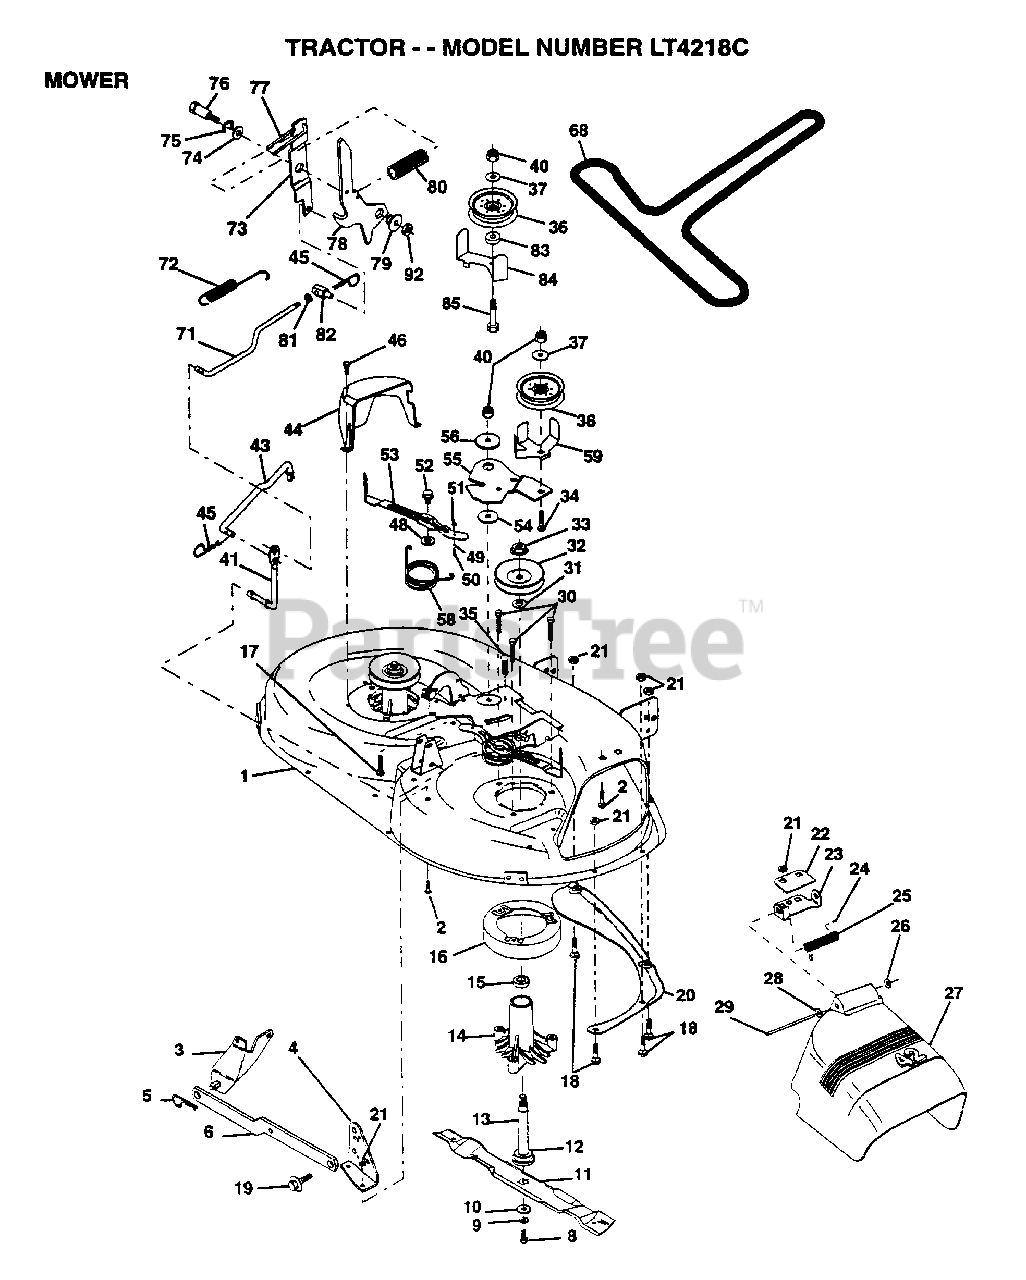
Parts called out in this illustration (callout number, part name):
1	DECK.WELD.42.
2	BOLT
3	BRKT ASM SWAY BAR
4	BRKT DECK SW BAR
8	BLADE BOLT
10	WASHER.HARD.BLADE
11	"BLADE.42"" HIPERF"
12	BEARING.BALL
14	HSG ASM MANDREL
15	BEARING
16	STRIPPER RND MWR
17	BOLT RDHD 3/8-16
18	BOLT
19	BOLT SHD 5/16-18
22	STIFFENER BRKT
23	DEFLECTOR BRKT
24	CAP-SLEEVE LT
25	SPRING TORSION
26	NUT PUSH M
27	DEFLECTOR.SHIELD
28	WASHER
29	HINGE ROD
31	WASHER
34	BOLT
35	XMAS TREE FASTNER
36	FLAT IDLER PULLEY
37	WASHER
41	PIVOT ROD
43	ROD CLUTCH W/NIBS
44	GUARD MAND LH BLK
45	RETAINER M
46	SCREW.1/4-20X5/8
48	HARD SMALL WASHER
50	SHOULDER BOLT
51	LOCKNUT
52	BOLT.SHLD.5/16-18
53	BRAKE PAD ARM ASM
54	HARDENED WASHER
56	SPACER RETAINER
58	SPRING TORSN BRAK
59	GUARD IDLER TUV
68	BELT.V.T-PATH
71	ROD CLUTCH 38/42
72	SPRING.EXT.RETURN
73	CLUTCH ARM SECOND
74	WASHER
75	RING
76	SHOULDER BOLT
77	SPRING KEEPER
79	BUSHING
81	NUT
82	TRUNION ADJ
83	WASHER
85	BOLT RDHD SQNK 3/8-16X2-1/2
92	NUT
